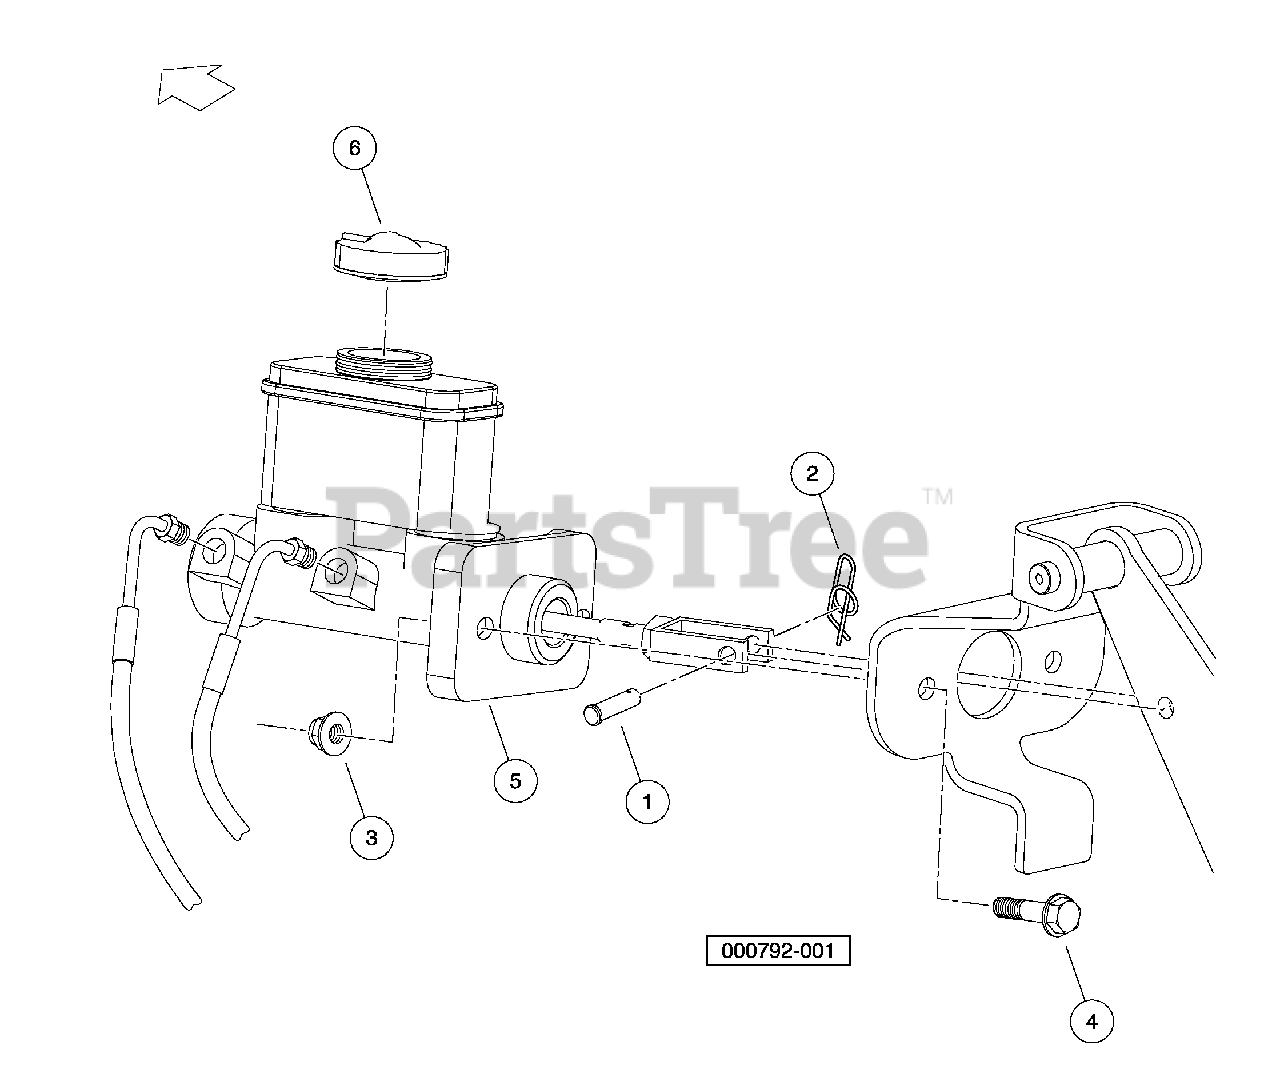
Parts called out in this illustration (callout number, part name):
1	Clevis Pin, 5/16 X 1
3	Nut,m8,all Metal Lock
4	Bolt Flanged Head, M8 X 1.25 X 35
5	Cylinder, Master, Integral Res
6	Filler Cap Asm Integral Res
